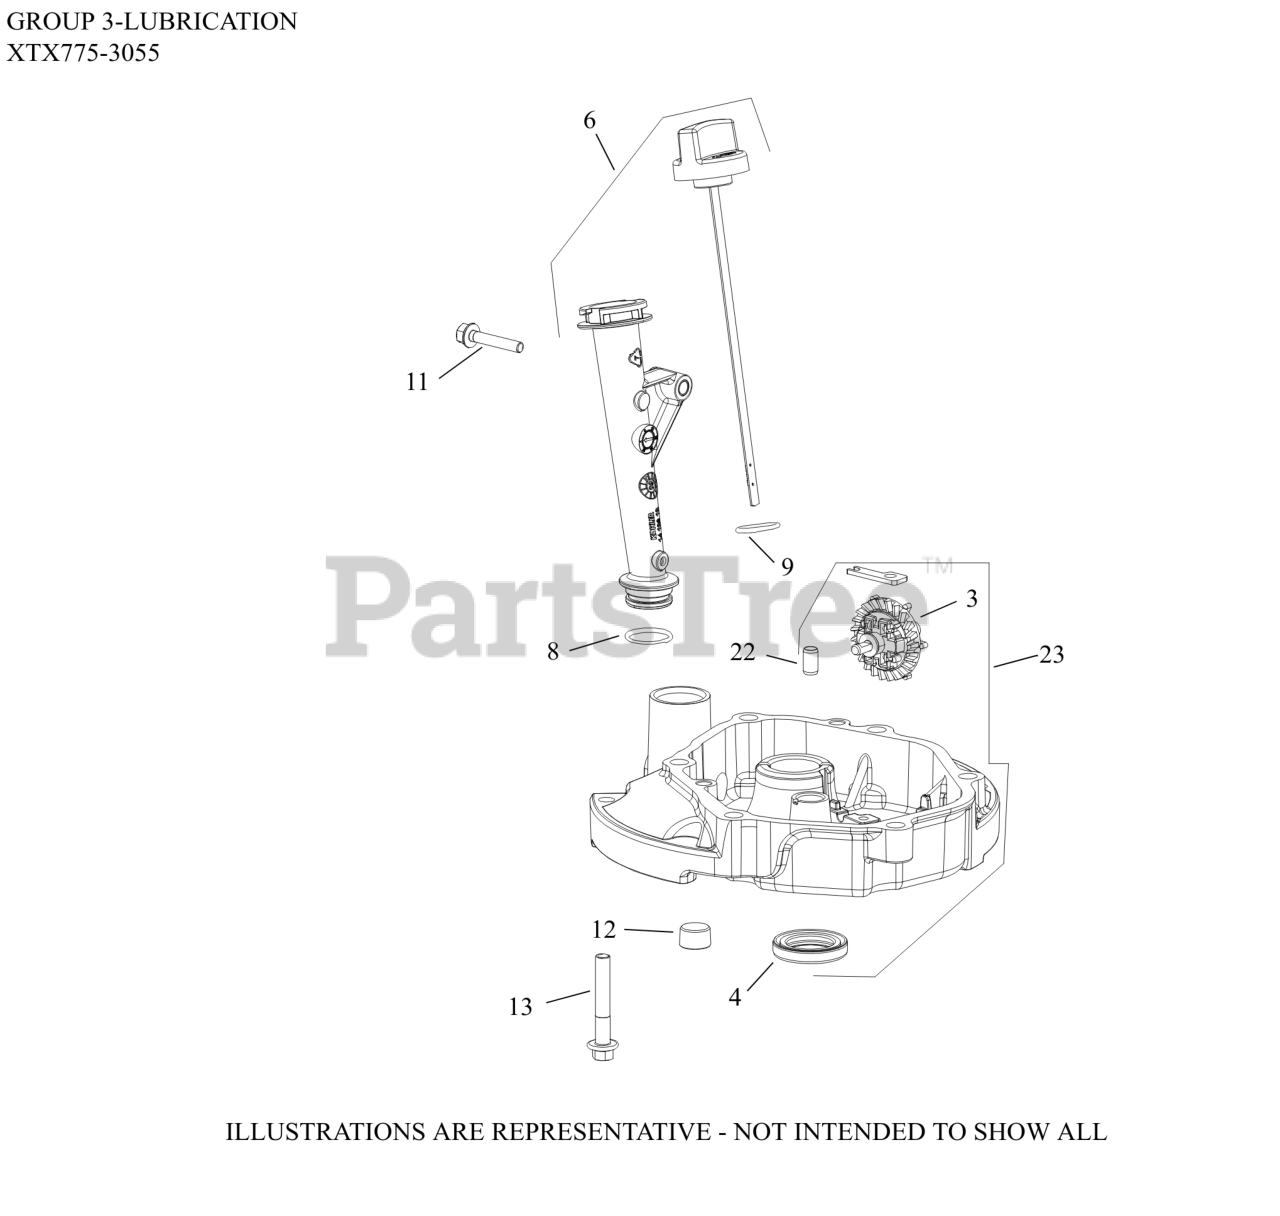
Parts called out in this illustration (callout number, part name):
3	GEAR ASSEMBLY, GOVERNOR
6	DIPSTICK AND TUBE ASSY
8	O-RING, OIL FILL TUBE
9	O-RING (CAP)
11	SCREW, HEX FLANGE (M6)-(#25086435S)
12	PLUG, PIPE (W/SEALANT)
13	SCREW, HEX FLANGE (M8)-USE 25 086 456-S
22	PIN, DOWEL (8mm)
23	KIT, OIL PAN
